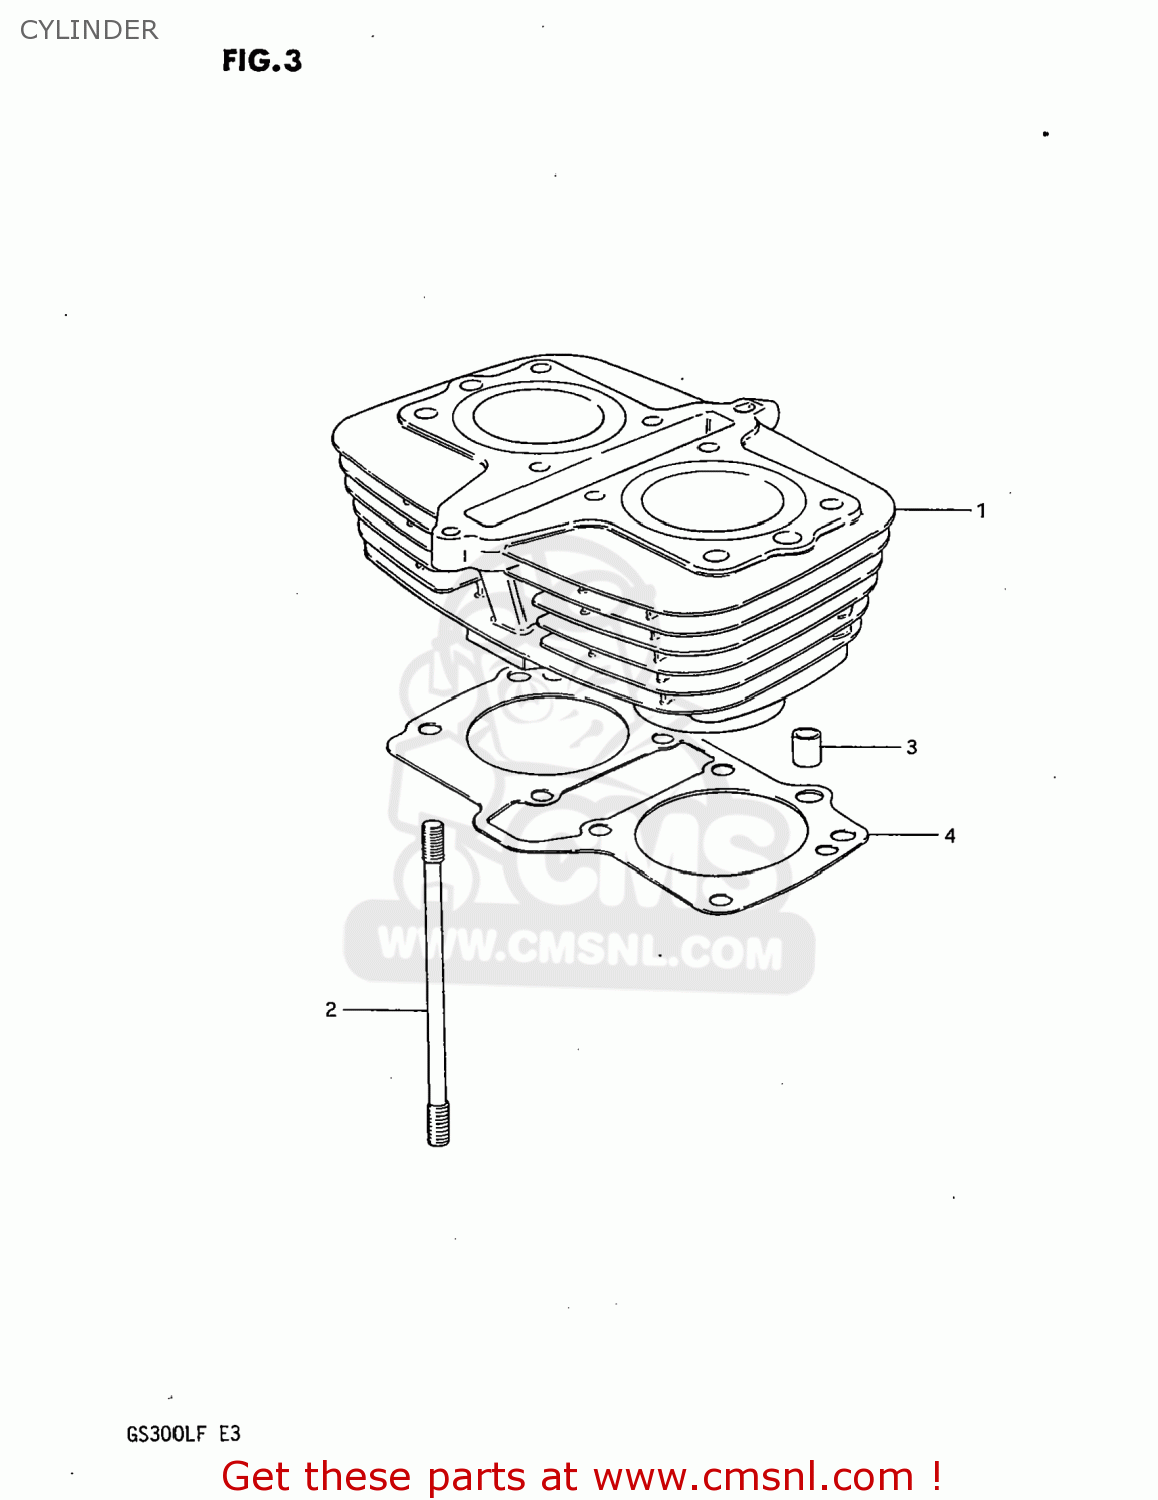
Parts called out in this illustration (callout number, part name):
1	CYLINDER
2	STUD
3	PIN
4	GASKET,CYLINDER
